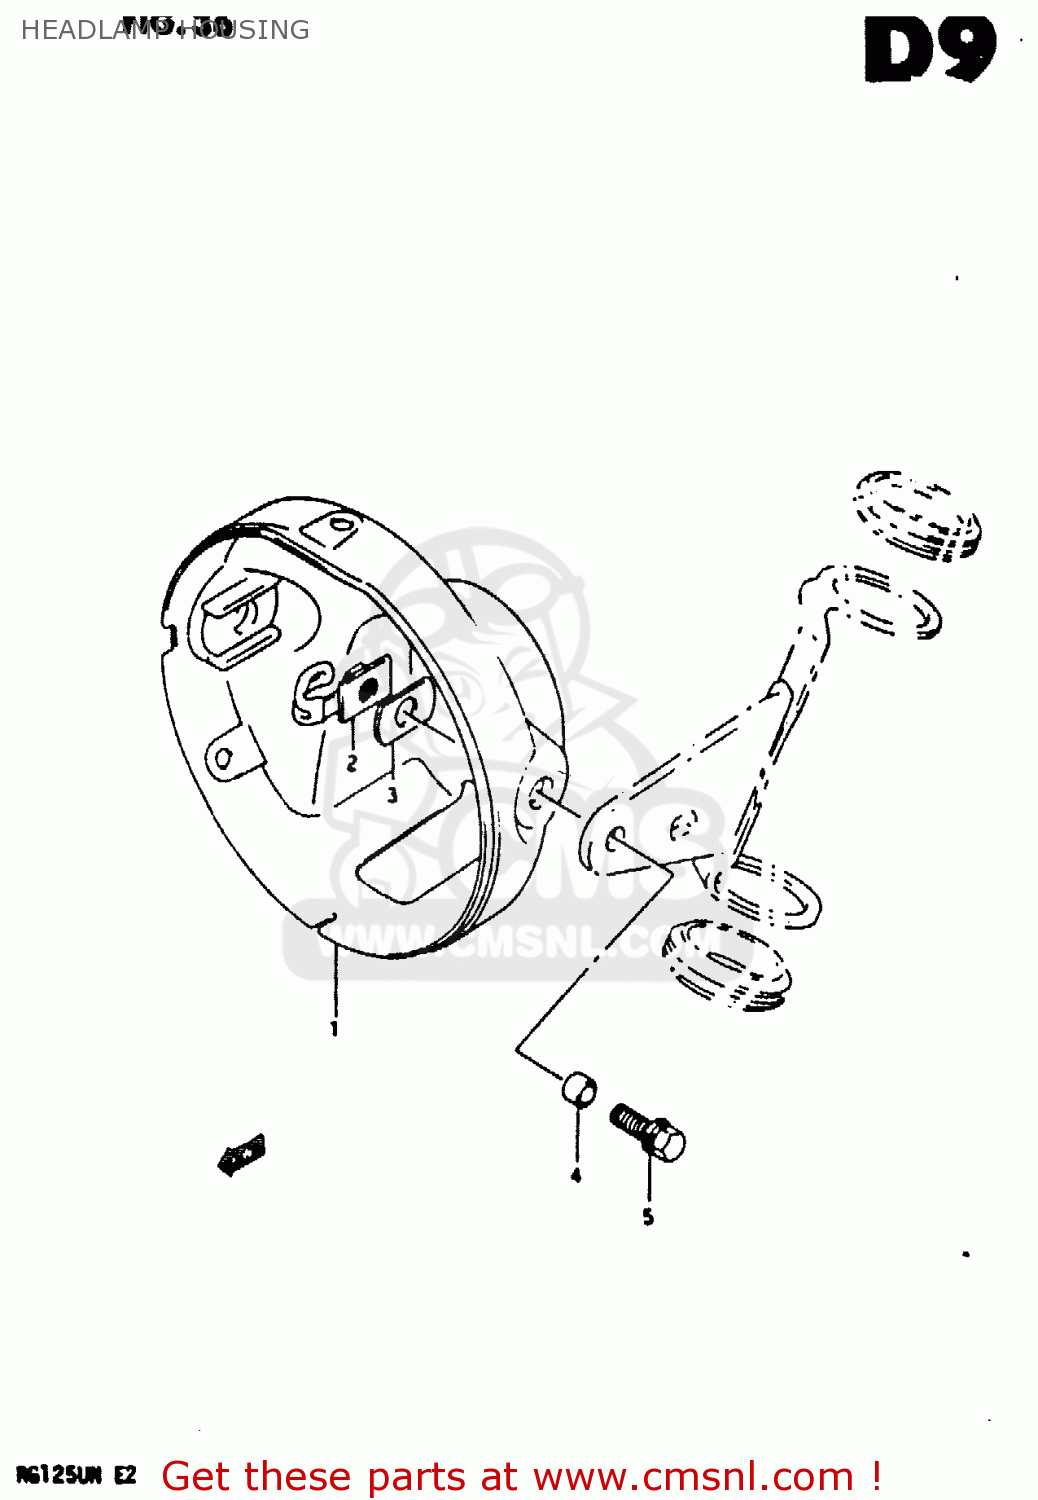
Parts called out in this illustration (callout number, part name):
1	HOUSING,HEADLAMP
2	PLATE,HEADLAMP HOUSING
3	CUSHION
4	SPACER (8.8X12X7)
5	BOLT
